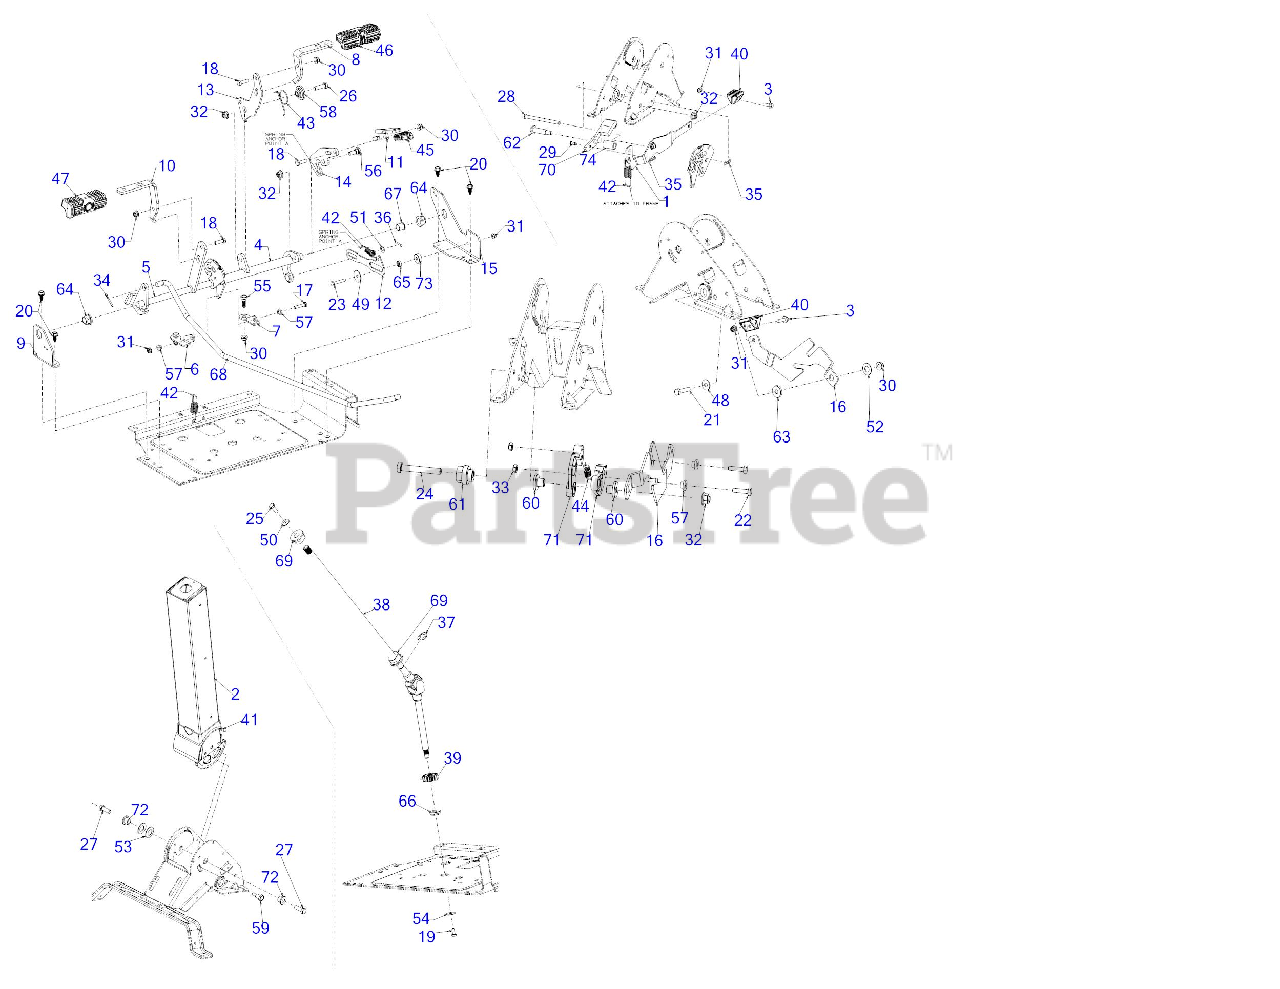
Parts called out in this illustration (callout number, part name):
3	HEX SCREW 1/4-20X.
4	DRIVE PEDAL SHAFT ASSEMBLY
5	BRAKE SHAFT ASSEMBLY
12	NEUTRAL RETURN LINK
13	FORWARD PEDAL BRACKET
14	REVERSE PEDAL PIVOT PLATE
17	HEX SCREW 1/4-20 x 1.25
18	SCREW 5/16-18 x 1.0 GR5
19	SCREW 1/4-20 x .62 SPEC GR5
20	SCREW 5/16-18 x .750
21	SCREW 5/16-18 x 1.25 GR5
22	SCREW 1/4-20 X1.00 GR5
23	SCREW 1/4-20 x 1.50 GR.5
24	HEX SCREW-3/8-16X2.5 GR5
25	SCREW 5/16-24 x .875 GR5
26	SCREW 3/8-16 x 1.25 GR5
27	SCREW 3/8-16X1.0 GR5
28	CLEVIS PIN 5/16 x 4.135
29	CLEVIS PIN .224 x .625
30	FLANGE LOCK NUT 5/16-18
31	FLANGE LOCK NUT
33	HEX NUT 1/4-20
34	COTTER PIN-5/32 DIA
35	BOW TIE COTTER PIN 1/4-5/16
36	COTTER PIN
37	E-RING
38	STEERING SHAFT ASSEMBLY
39	STEERING GEAR 14T
40	CRUISE TILT KNOB
41	STEERING COLUMN COVER
42	EXTENSION SPRING
43	TORSION SPRING
44	EXTENSION SPRING .40 ODx1.50 LG
45	REVERSE PEDAL PAD
46	FORWARD PEDAL PAD
47	BRAKE PEDAL PAD
48	FLAT WASHER
49	FLAT WASHER
50	BELL WASHER .337 X.867 x .057
51	WASHER THRUST .375X.70X.030
52	FLAT WASHER .508X1.000X.040
53	BELLEVILLE WASHER 1.24X.642X.049
54	FLAT WASHER
55	SHOULDER SCREW .437
56	SHOULDER SCREW
57	SHOULDER SPACER
58	SHOULDER SPACER 1.50X.38X.38
59	SHOULDER BOLT .395 DIA x .56 LG
60	SHOULDER SPACER .500X1.00X.440
61	TILT ADJUSTMENT BUSHING
62	SHOULDER SCREW .496X1.44 3/8-16
63	SHOULDER SPACER
64	FLANGE BEARING
65	BALL BEARING .25 x .625 SPCL
66	HEX FLANGE BEARING 7/16
67	NYLINER BEARING
68	FRONT BRAKE ROD
69	FLANGE BEARING
70	CRUISE LATCH
71	TILT STEERING PAWL
72	SHOULDER SPACER .381X.626X.414
73	SPACER .267X1.00X.36
74	SPACER 0.510 X 0.775 X 1.190
